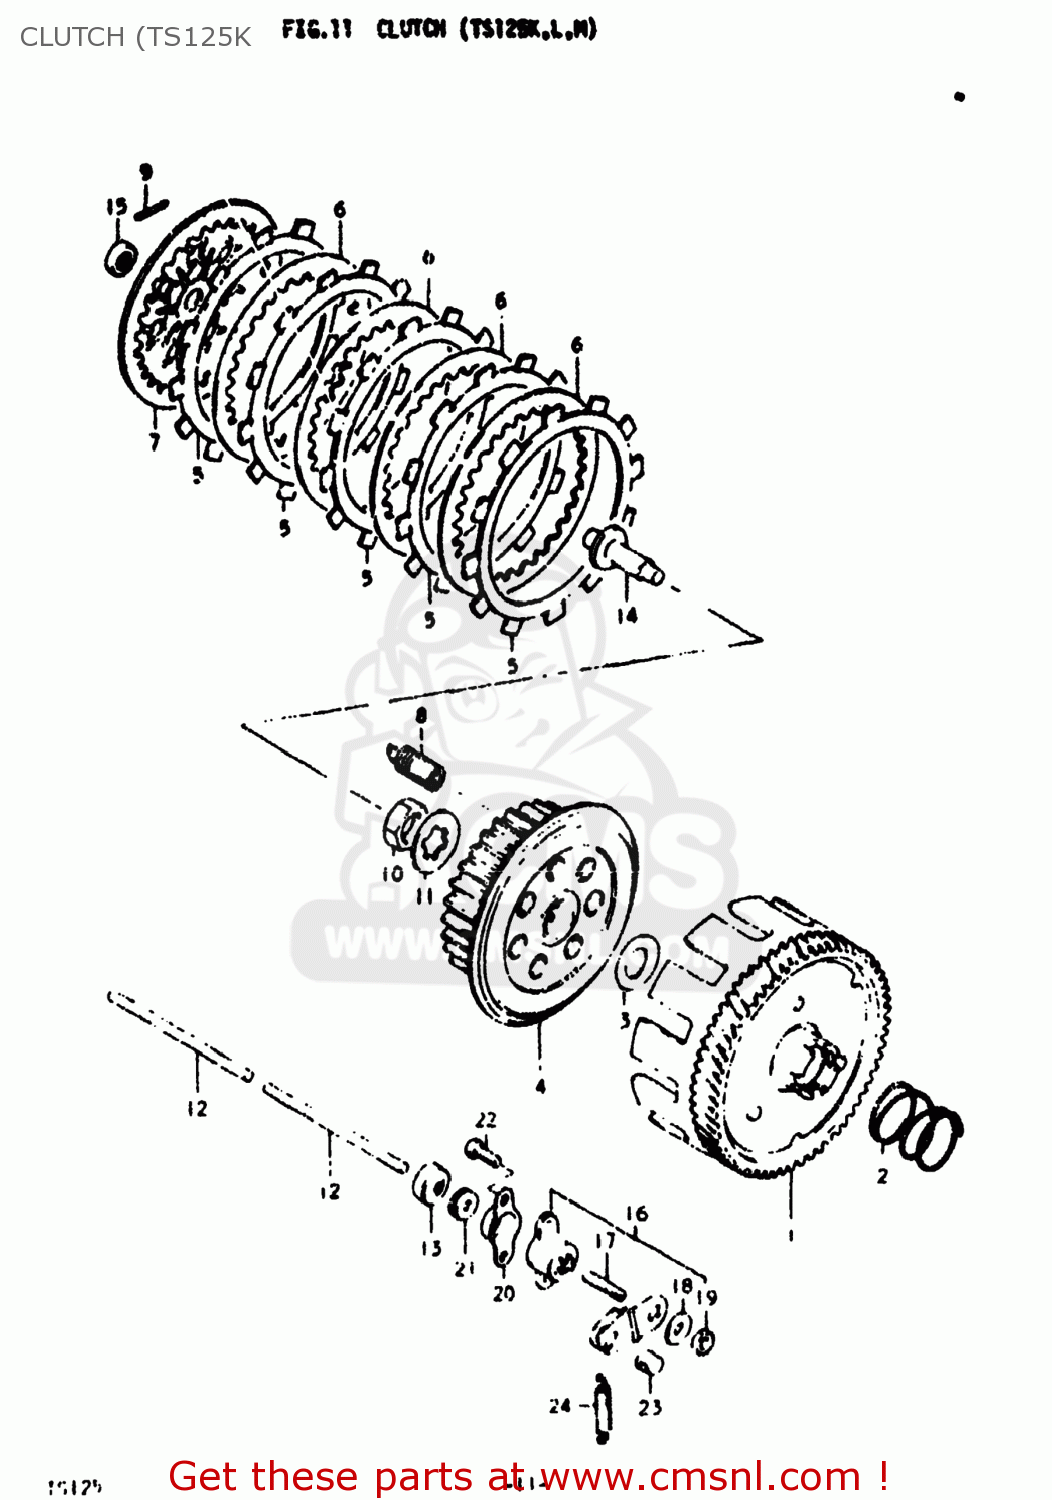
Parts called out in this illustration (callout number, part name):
1	GEAR ASSEMBLY,PRIMARY DRIVE
2	SPRING
3	WASHER
4	HUB,CLUTCH SLEEVE
5	PLATE,CLUTCH DRIVE
6	PLATE,CLUTCH DRIVEN (NAS)
7	PLATE,CLUTCH PRESSURE
8	SPRING
9	PIN(2.5X19.8)
10	NUT
11	WASHER,LOCK
12	ROD,CLUTCH PUSH
13	OIL SEAL
14	ROD,CLUTCH RELEASE
15	SEAL,OIL (10X17X5)
16	SCREW ASSY,CLUTCH RELEASE
17	SCREW
18	WASHER(6.5X16X1.2)
19	NUT
20	COVER,CLUTCH RELEASE SCREW
21	SEAL,DUST(5.3X13X5)
22	SCREW
23	PIECE,RELEASE ARM END
24	SPRING
